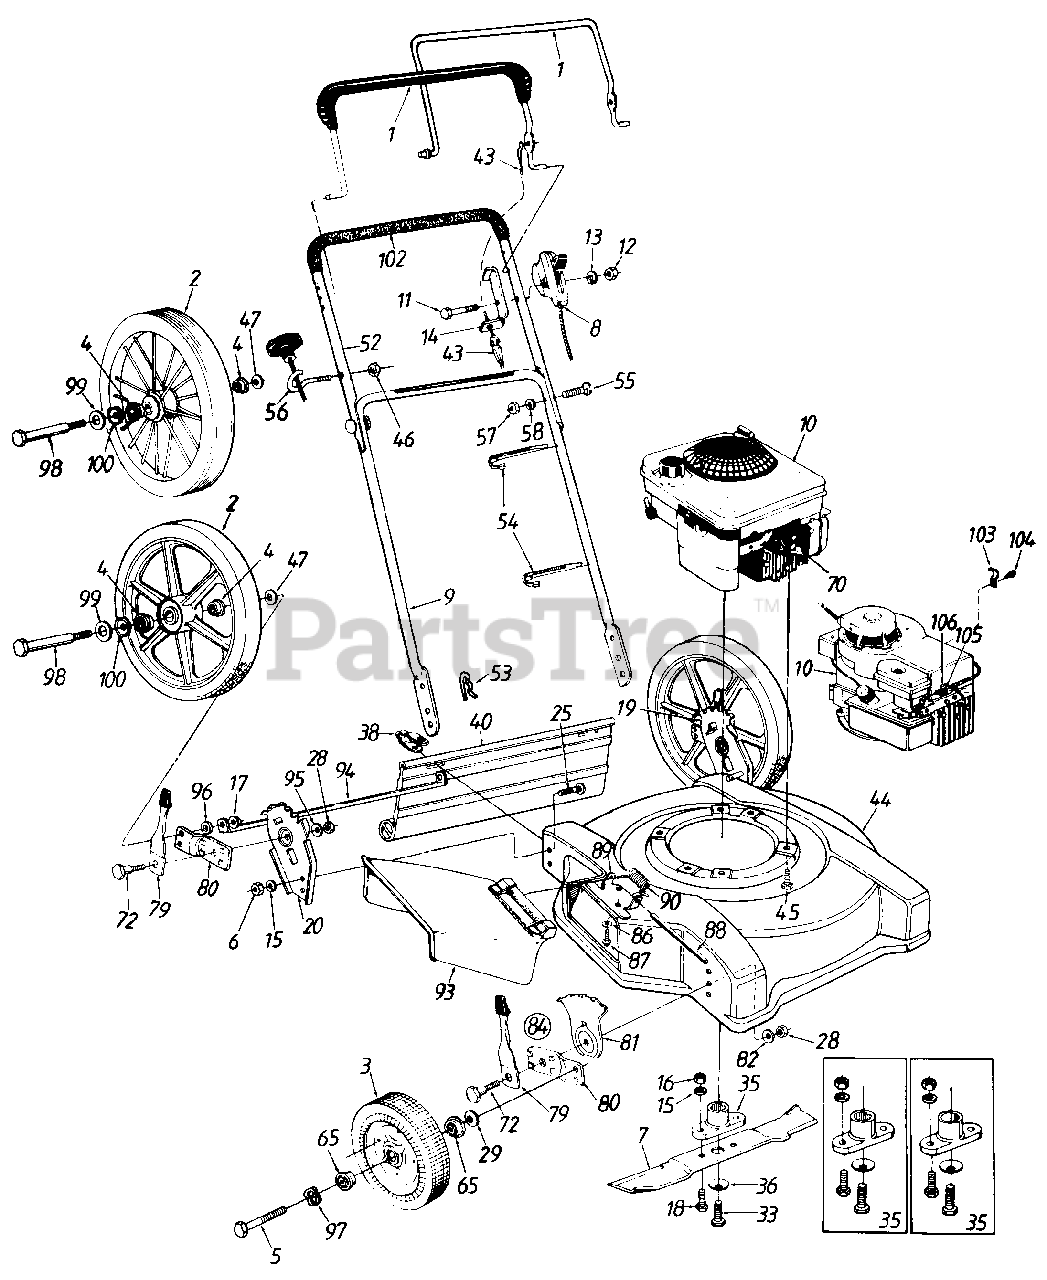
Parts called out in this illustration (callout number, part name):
1	Control Handle
2	14" Wheel Ass'y. (Plastic)
3	Front Wheel Ass'y.
4	Bearing 1/2" I.D.
5	Front Axle Bolt
6	Hex Nut 3/8-24 Thd.
7	20" Blade
8	Throttle Control
9	Lower Handle
10	Engine
11	Hex Bolt 1/4-20 x 1.875" Lg.
12	Hex Nut 1/4-20 Thd.
13	Spr. Wash. .265" I.D. x .562"
14	Cable Mtg. Bracket
15	L-Wash. 3/8" I.D.
16	Hex Nut 3/8-24 Thd.
17	Flange L-Nut 3/8-18 Thd.
18	Hex Bolt 3/8-24 x 1.0" Lg.
19	Wheel Brkt. Ass'y.-L.H.
20	Wheel Brkt. Ass'y.-R.H.
25	Ribbed Neck Bolt 3/8-24 x .80"
28	Hex Nut 3/8-16 Thd.
29	Bell-Wash. .400" I.D. x .88"
33	Hex Bolt 3/8-24 x 1.5" Lg.
35	Blade Adapter Kit (Keyed)
36	Bell-Wash. .39" I.D.
38	Hinge Clip
40	Rear Flap Ass'y.
43	Control Cable-39"
44	638/N 20" Deck Ass'y.
45	Hex Wash. Hd. TT-Tap Scr. 3/8-16 x 1.00" Lg.
46	Hex Nylon L-Nut 1/4-20 Thd.
47	Bell-Wash. .38" I.D. x .88"
52	Upper Handle
53	Intern. Cot. Pin 5/16" Dia.
54	Cable Tie
55	Curved Carriage Bolt 5/16-18 x 1.38" Lg.
56	Rope Guide
57	Hex Nut 5/16-18 Thd.
58	L-Wash. 5/16" I.D.
65	Bearing
70	Spark Plug Boot
72	Shoulder Bolt .50" Dia.
79	Spring Lever Ass'y. w/Knob
81	Height Adj. Plate
82	Bell-Wash. .39" I.D. x 1.38"
84	Front Height Adj. Ass'y. Comp.-R.H.
86	Bell-Wash. .285" I.D. x .75"
87	Hex Wash. Hd. Tap Scr. 1/4-20 x .5" Lg.
88	Hinge Pin
89	Adapter Plate
90	Torsion Spring
93	Chute Deflector Ass'y. Comp.
94	Stabilizer Tube
96	Spacer .503" I.D. x .75"
97	Wave Washer .53" I.D.
98	Rear Axle Bolt
99	Fl-Wash. .51" I.D. x 1.372"
100	Spr. Wash. .5" I.D. x 1.0"
102	Foam Grip
103	Casing Clampt
104	Hex B-Tap Scr. #10 x .38"
105	Casing Clamp
106	Hex AB-Tap Scr. #8 x .50"
